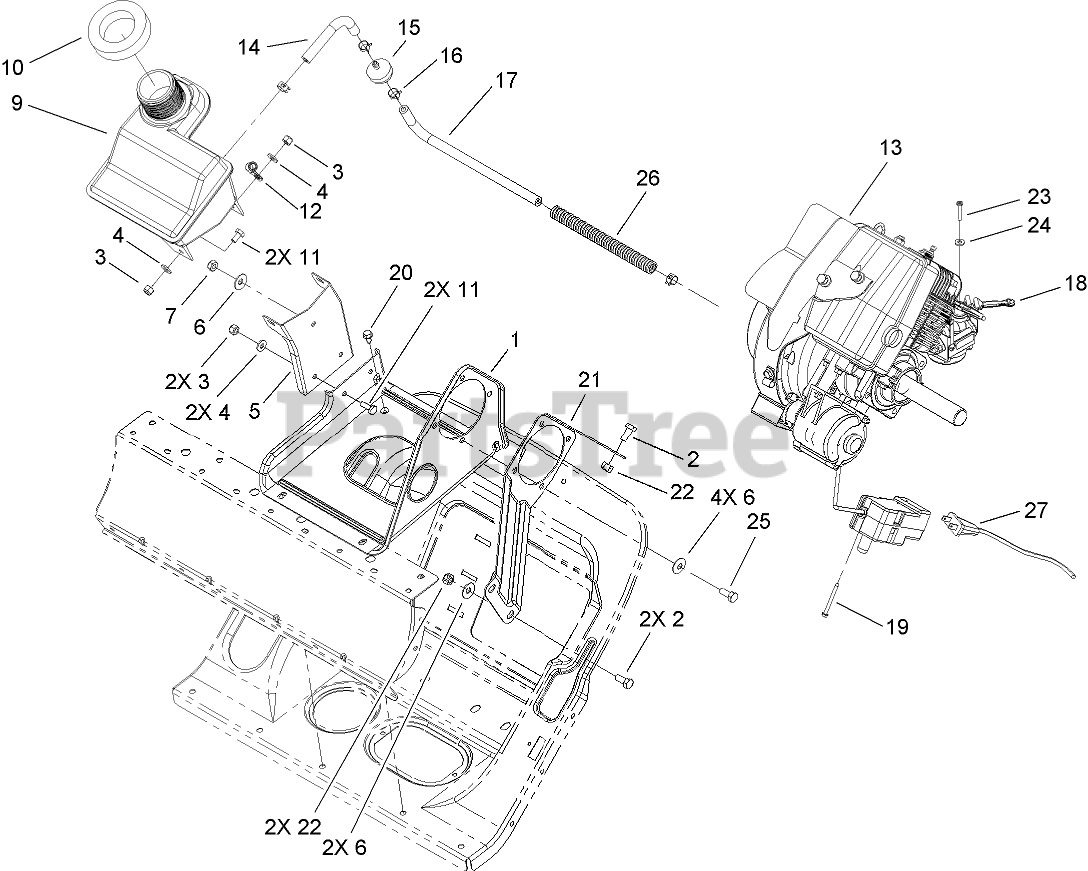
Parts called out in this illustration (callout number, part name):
1	SUPPORT-ENGINE
2	SCREW-HH
3	NUT-LOCK, NI
4	WASHER-FLAT
5	SUPPORT-RECOIL
6	WASHER-BELLEVILLE
7	NUT-LOCK, NI
9	Tank-Gas
10	SEAL-FOAM
11	SCREW-HH
12	CLAMP
14	HOSE-FUEL
15	FILTER-FUEL
16	CLAMP-HOSE
17	LINE-FUEL
18	LEVER-CHOKE
19	SCREW-PLASTITE
20	SCREW-HWH, THREAD ROLL
21	BRACE-ENGINE
22	NUT-LOCK, NI
23	SCREW-PPH, PLASTITE
24	WASHER-FLAT
25	SCREW-HH
26	CONDUIT
27	CORD-ELECTRIC
